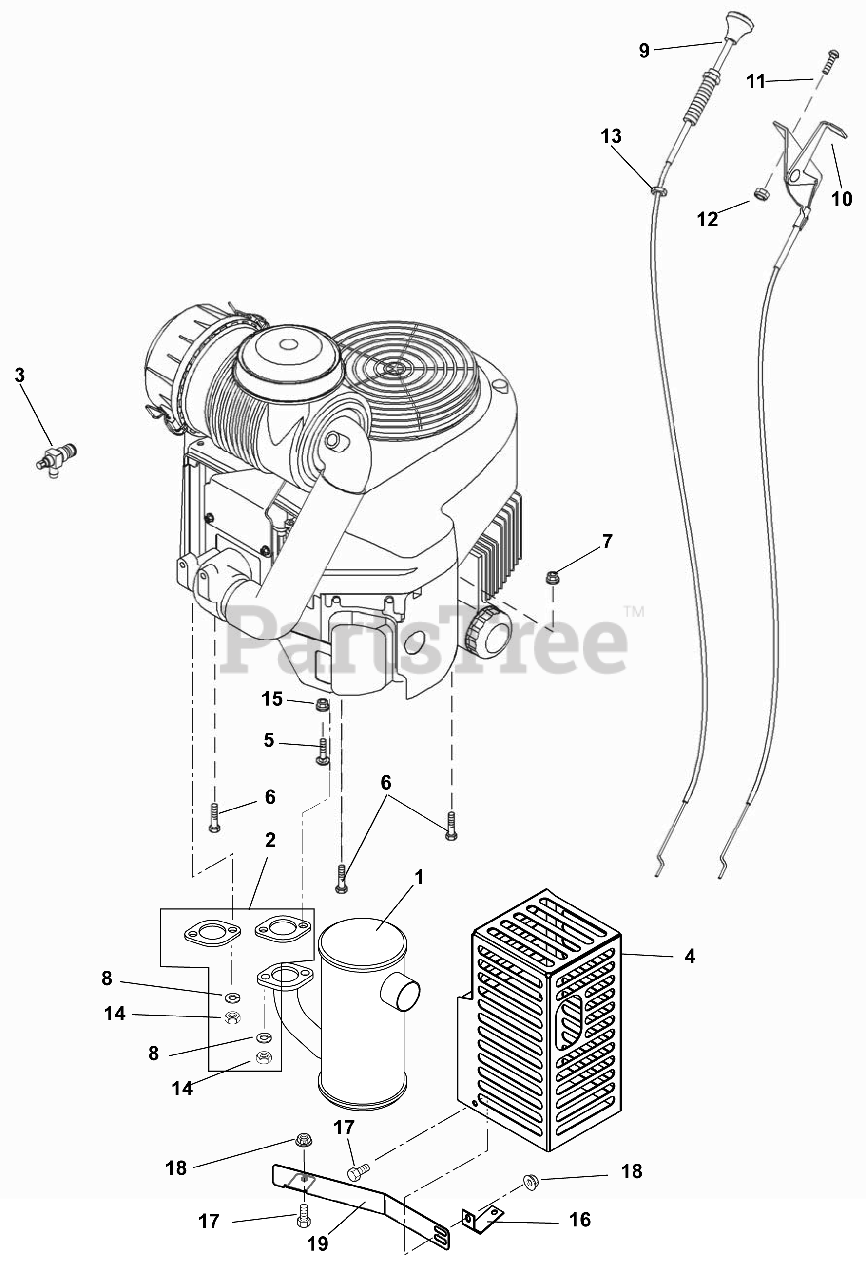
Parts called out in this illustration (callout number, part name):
1	MUFFLER
2	GASKET KIT, INCLUDES ITEMS 2,8
3	OIL DRAIN FITTING
4	WMT-MUFFLER GUARD - PRO-STANCE
5	BLT, RDHDSQNK, M8X1.25X40
6	CAP SCREW, ENG MNTING M8 X 1.2
7	@NUT-LK-NYL M8-1.25 YWZC
8	@WSHR-LK .31X.078 REG YWZC
9	CABLE, CHOKE
10	CABLE, THROTTLE
11	@BLT-HEX 8-32 X .5 YWZC
12	@NUT-LK-NYL 8-32 W/INSTR YWZC
13	@NUT-HEX .38-16 YWZC
14	NUT-HEX M8-1.25 YWZC
15	NUT-LK-FLG M8-1.25 YWZC
16	BRACKET, MUFFLER GUARD
17	@BLT-HEX .31-18X.75 GR5 YWZC
18	@NUT-LK-TOP-FLG .31-18 YWZC
19	SHIELD - MANIFOLD
